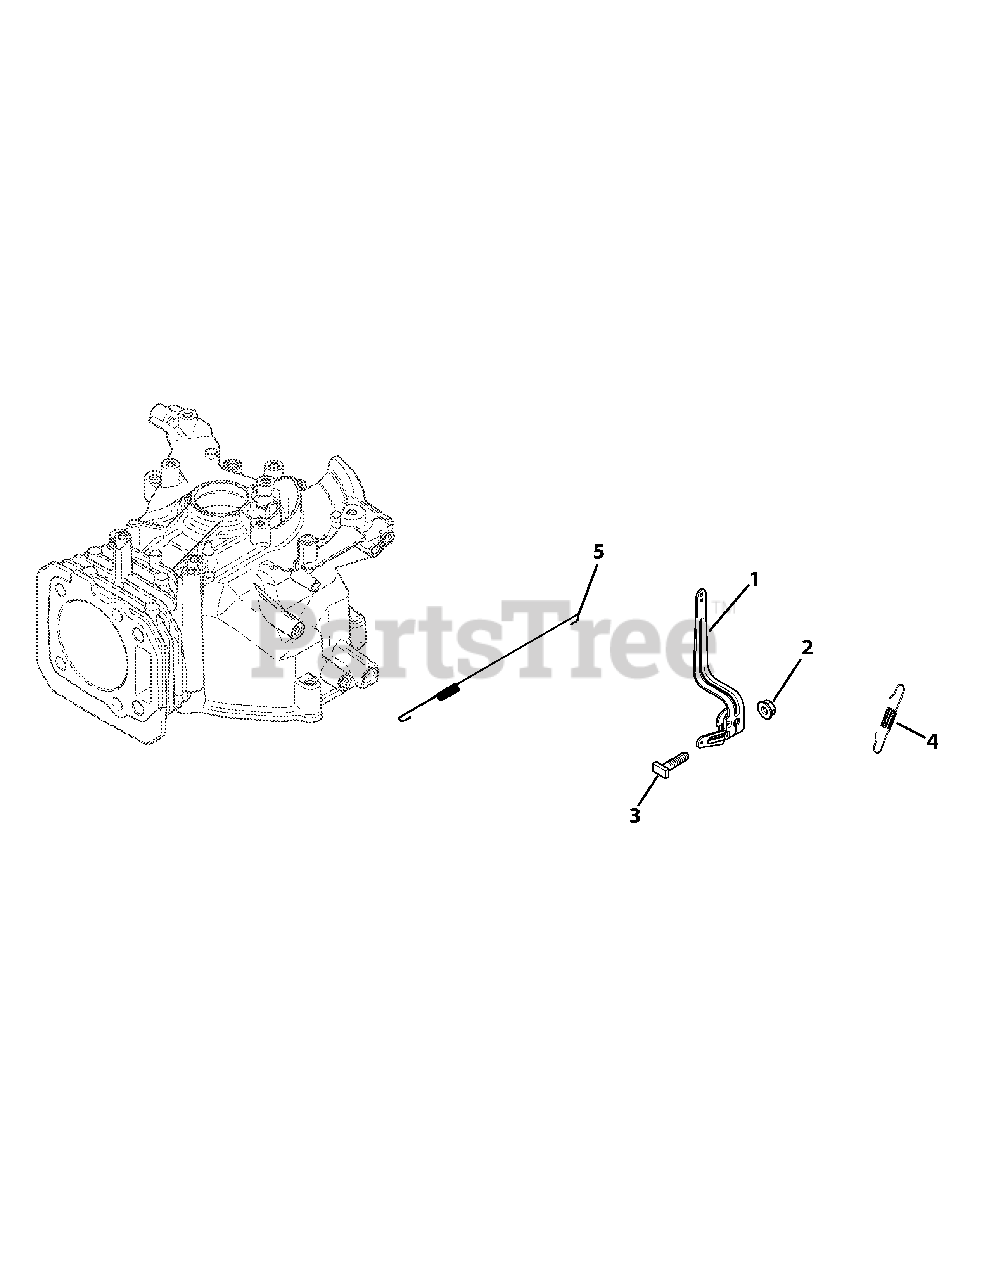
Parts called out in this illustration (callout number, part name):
1	Governor Lever
2	Hex Flange Nut, M6
3	Rectangle Head Screw, M6
4	Governor Spring (2800-3300 RPM)
5	Linkage Spring
